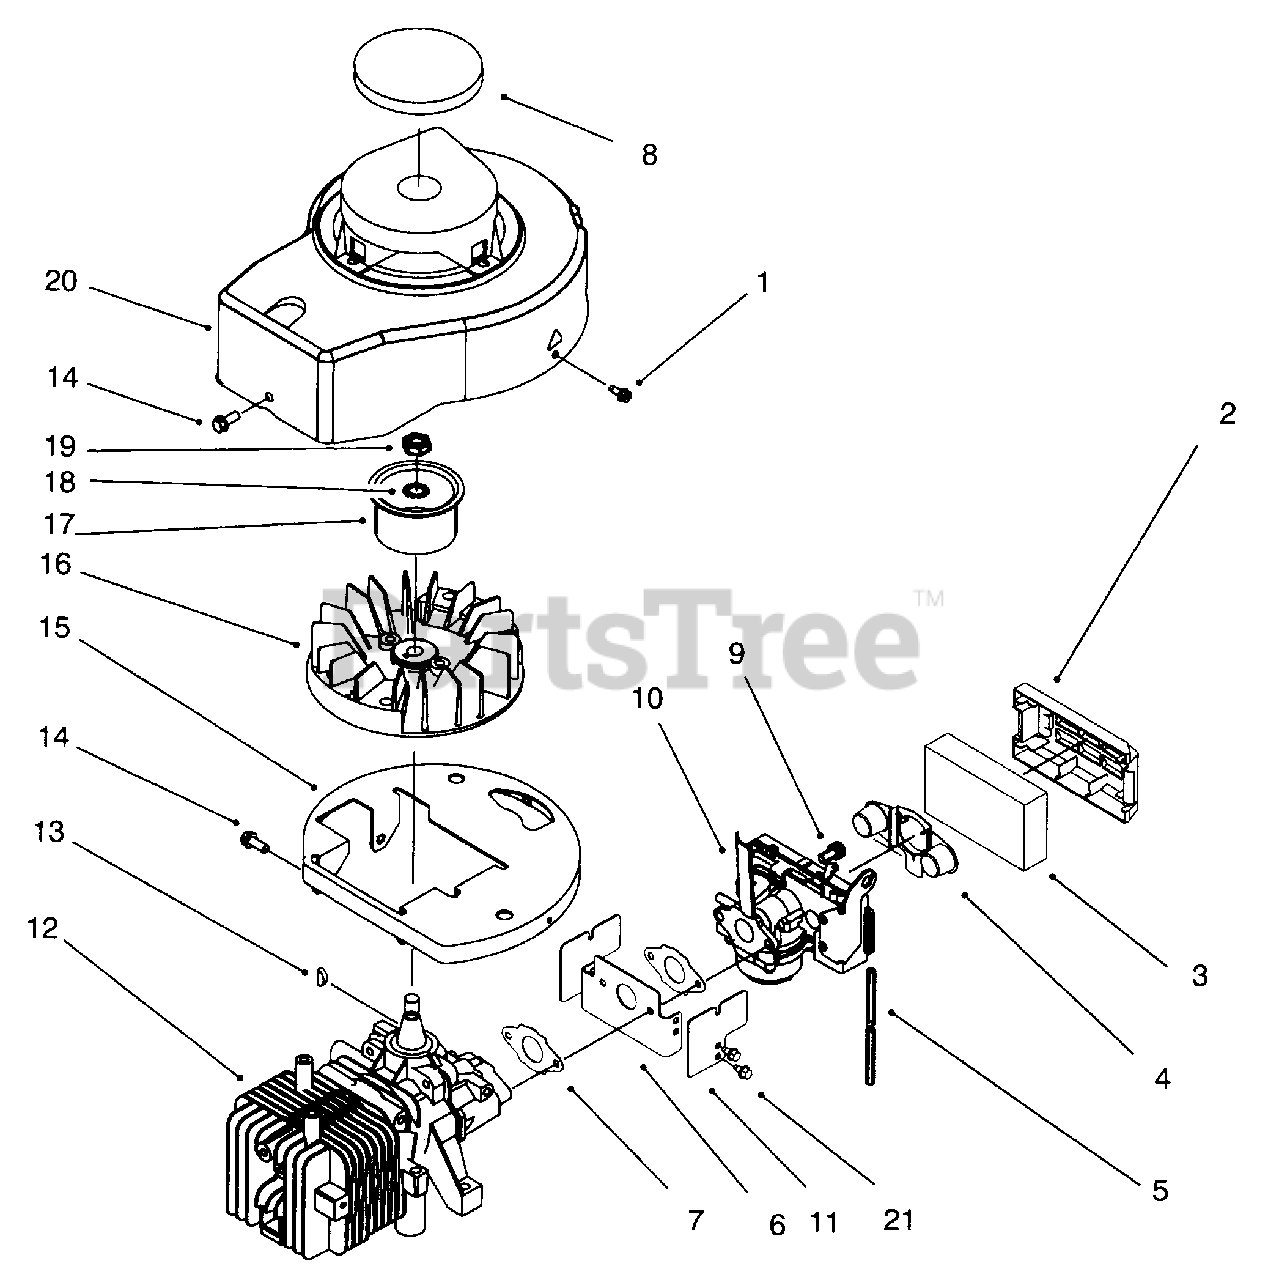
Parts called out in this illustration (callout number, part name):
2	Cover-Air Filter
3	Element-Air Filter
4	Shield-Fuel
5	Hose-Primer
6	Shield-Carburetor
7	Gasket-Carburetor
8	Disc-Foam
10	Carburetor Assembly
11	Shield-Governor
12	Short Block Assembly
14	Screw
15	Base-Shroud
16	Flywheel Assembly
17	Hub-Starter
18	Washer-Lock
20	Shroud
